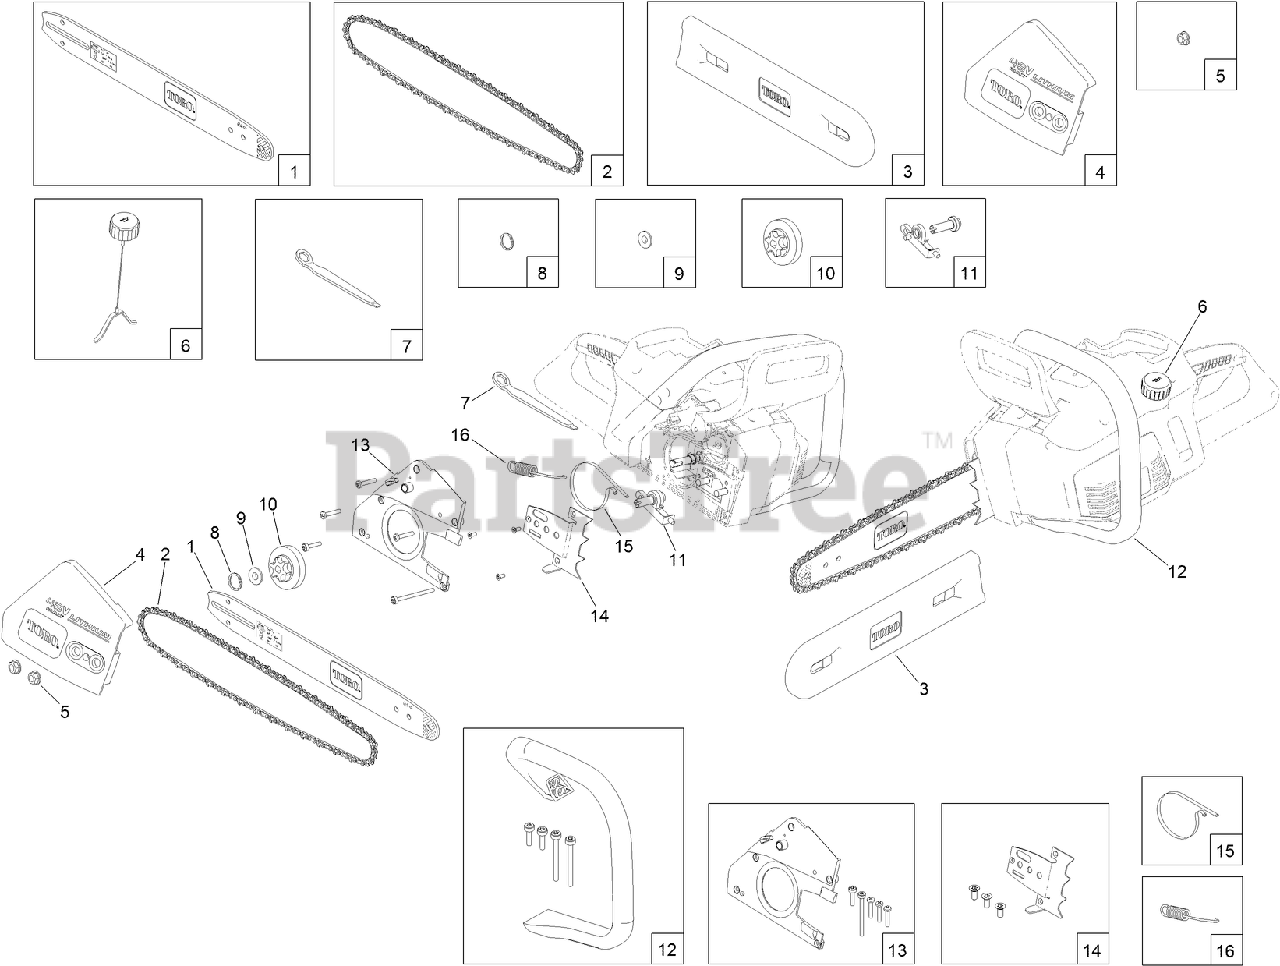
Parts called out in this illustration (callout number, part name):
1	BAR-REPLACEMENT
2	CHAIN-REPLACEMENT
3	SLEEVE-BAR
4	COVER-BAR/CHAIN
5	NUT-M8
6	OIL CAP ASM
7	WRENCH
8	SNAP-RING
9	SPACER
10	SPROCKET
11	BAR AND CHAIN ADJUSTER ASM
12	HANDLE ASM
13	INTERNAL COVER ASM
14	BUCKING TEETH BRACKET ASM
15	BRAKE-BAN
16	SPRING-LEVER, BRAKE
